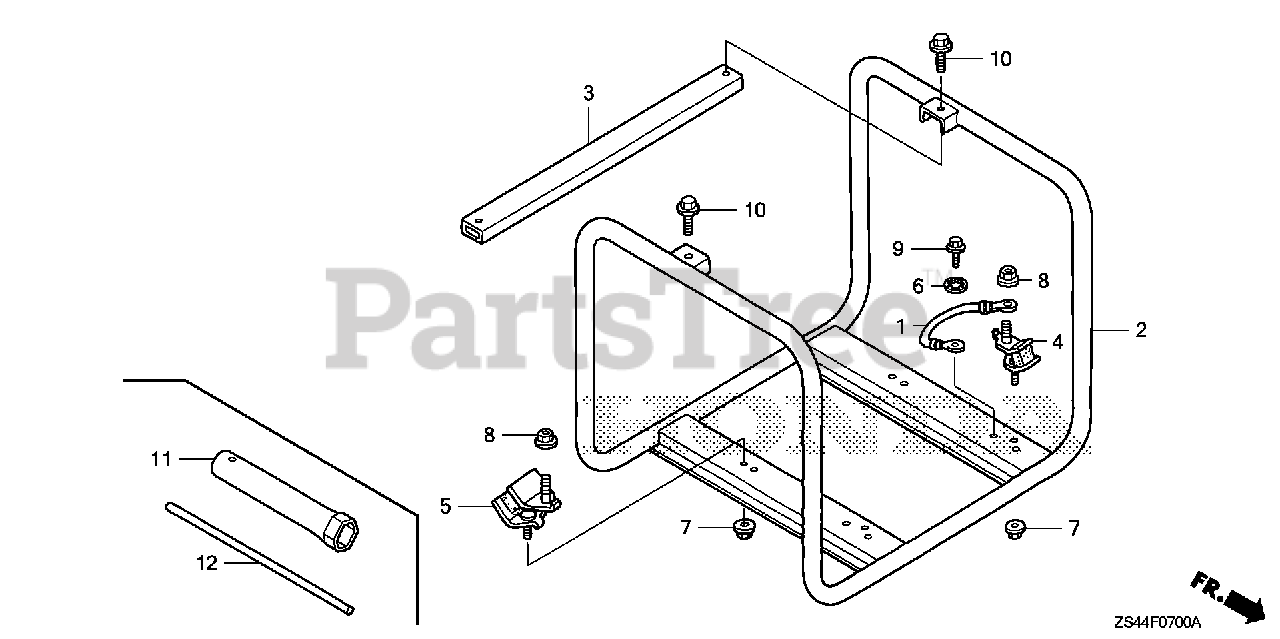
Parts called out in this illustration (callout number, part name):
1	CABLE, GROUND
2	FRAME *NH105* (MAT BLACK)
3	BAR, FRAME JOINT *NH105* (MAT BLACK)
4	RUBBER (LOWER)
5	RUBBER (LOWER)
6	WASHER, LOCK (6MM)
7	NUT, FLANGE (8MM)
8	NUT, FLANGE (10MM)
9	BOLT, FLANGE (6X10)
10	BOLT, FLANGE (8X16)
11	WRENCH, BOX (P21)
12	BAR A, HANDLE
